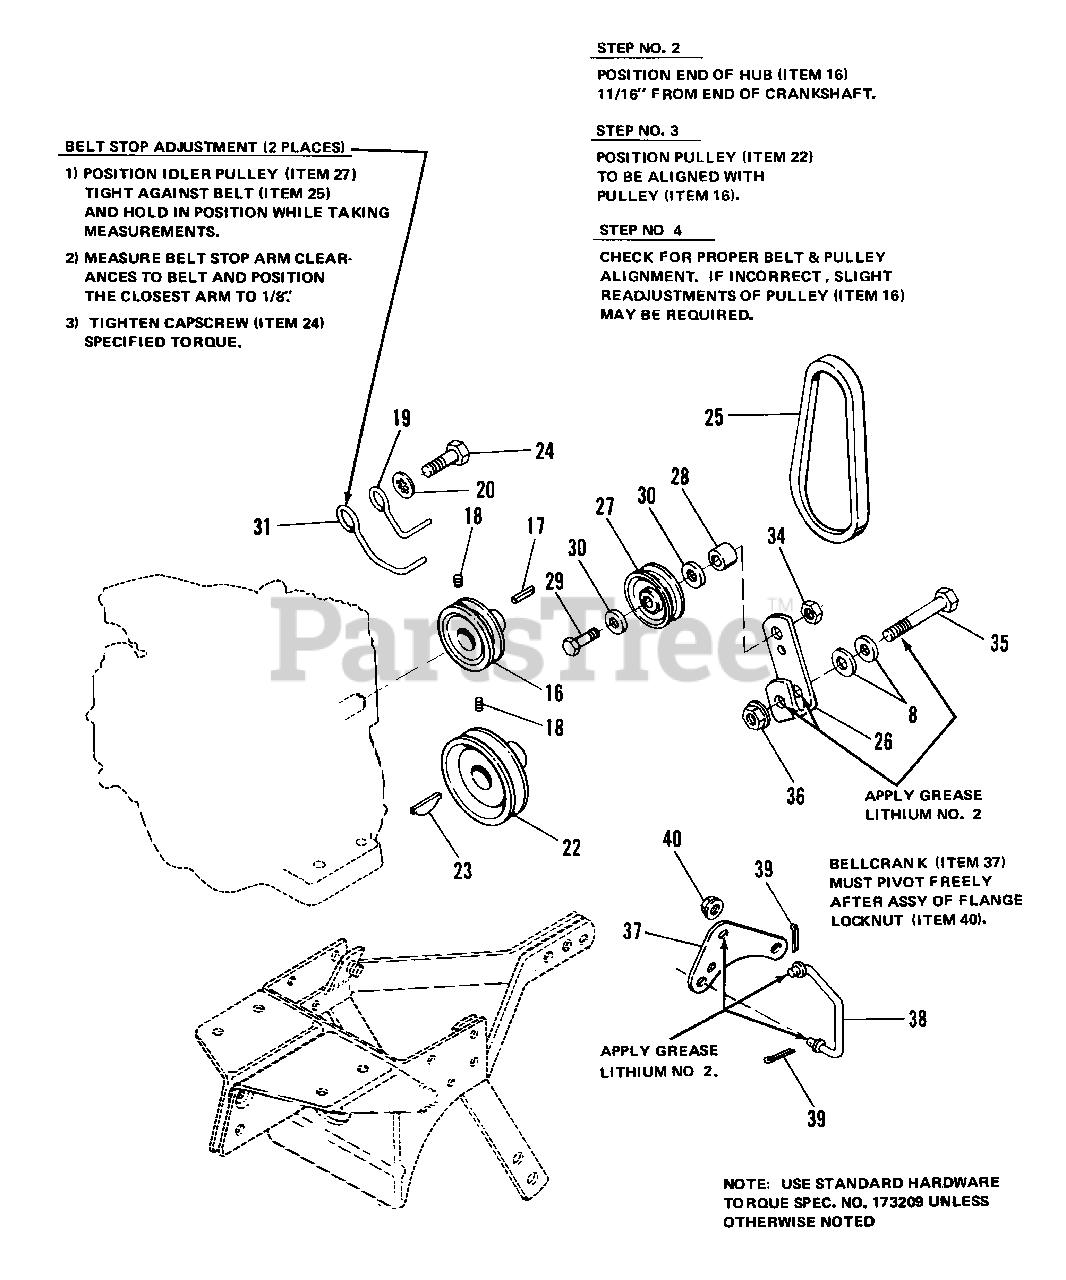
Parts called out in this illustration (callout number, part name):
1	FRAME ASSY
2	STOP, Plate
3	CAPSCREW, Hex, 3/8-16 x 1-1/2
4	LOCKWASHER, 3/8
5	NUT, Hex, Full, 3/8-16
6	WHEEL & TIRE ASSY
7	CAPSCREW, Hex, 1/2-13 x 3-1/2
8	WASHER, Plain, 1/2
9	NUT, Hex, Jam, 1/2-13
12	CAPSCREW, Hex Hd., 5/16-18 x 1-3/4
13	LOCKWASHER, 7/16
14	DECAL, Simplicity
15	NUT, Hex, 5/16-18
16	PULLEY, Engine, Forward
17	KEY, Sq., 3/16 x 1
18	SCREW, Set, 5/16-18 x 5/16
20	LOCKWASHER, 1/2, Int. Tooth
21	NUT, Hex, Full. 7/16-20
22	PULLEY, Worm Gear
24	CAPSCREW, Hex, 1/2-20 x 1
25	BELT, Forward
26	LEVER, Idler Pulley
27	PULLEY, Idler, Forward
29	CAPSCREW, Hex, 3/8-16 x 1-3/4
30	WASHER, Plain, 5/16
31	STOP, Belt
32	LOCKWASHER, Spring, 5/16
33	CAPSCREW, Hex, 7/16-20 x 1-1/4
34	LOCKNUT, Hex, Jam, 3/8-16
35	BOLT, Pivot
36	LOCKNUT, Flange, Whiz
37	BELLCRANK
38	LINK, Rod
39	PIN, Cotter, 1/16 x 24
40	LOCKNUT, Hex, Flange
41	CAPSCREW, Hex, 3/8-16 x 3/4
42	DECAL, Roticul, L.H.
43	COVER, Engine
44	SCREW, Taptite, 1/4-20 x 3/8
45	DECAL, 1003
46	DECAL, Roticul, R.H.
47	I.D. PLATE
48	BUSHING, Wheel
